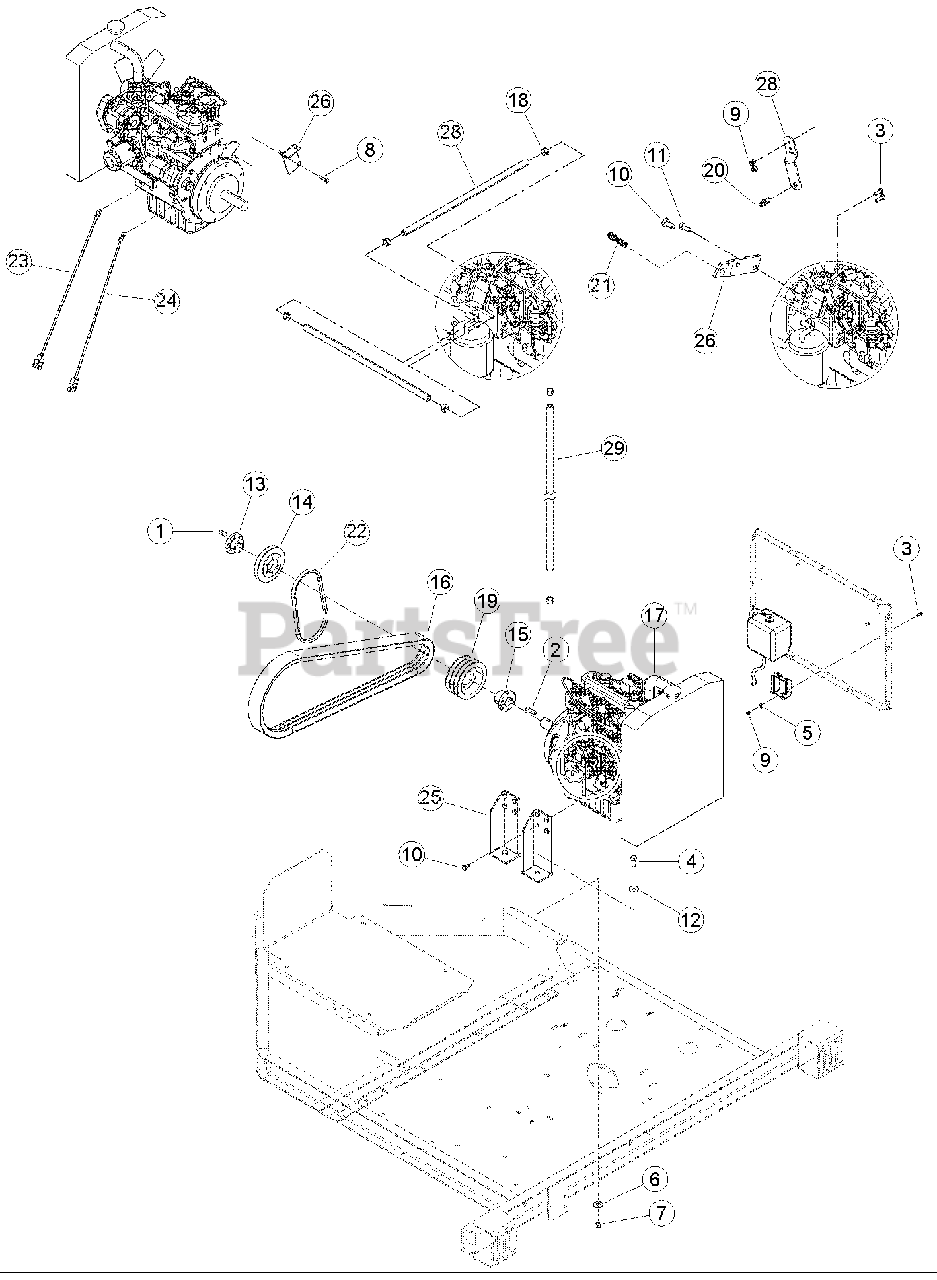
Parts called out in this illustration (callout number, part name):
1	KEY, 3/8 SQUARE X 1-1/4 LONG
2	KEY, 3/8 SQUARE X 1-3/4 LONG
3	BOLT, 1/4 X 3/4 HEX HD GR5 ZP
4	BOLT, 1/2 X 1-1/4 HEX HD GR5 ZP
5	WASHER, 1/4 FLAT ZP
6	WASHER, 1/2 FLAT ZP
7	NUT, 1/2 CENTERLOCK GRB ZP
8	BOLT, 5/16 X 1 CRG GR5 ZP
9	NUT, 1/4 NE NYLOCK ZP
10	BOLT, M 10-1.25 X 20 HHD GR8.8 ZP
11	BOLT, M 8-1.25 X 20 HHD GR8.8 ZP
12	WASHER, 1/2 HI-STRENGTH SAE ZP
13	BUSHING, SDS 1-7/16
14	SHEAVE, 1B5.2 SDS
15	BUSHING, SD 1-7/16
16	BELT, 3B83 BANDED
17	ENGINE, KUBOTA DIESEL 1.1L
18	CLAMP, 9/16 SPRING
19	SHEAVE, 3BQ5.6 SD
20	CABLE STOP, BOWDEN PIN #6170
21	BULKHEAD FITTING
22	BELT, BX30
23	CABLE, 72 IN. POSITIVE BATTERY
24	CABLE, 72 IN. NEGATIVE BATTERY
25	WELDMENT, ENGINE MOUNT
26	ANGLE, SPRING ANCHOR
27	STRIP, CABLE ANCHOR
28	HOSE, 15 IN. FUEL LINE
29	STRIP, THROTTLE CONTROL
30	HOSE, 38 IN. FUEL LINE
